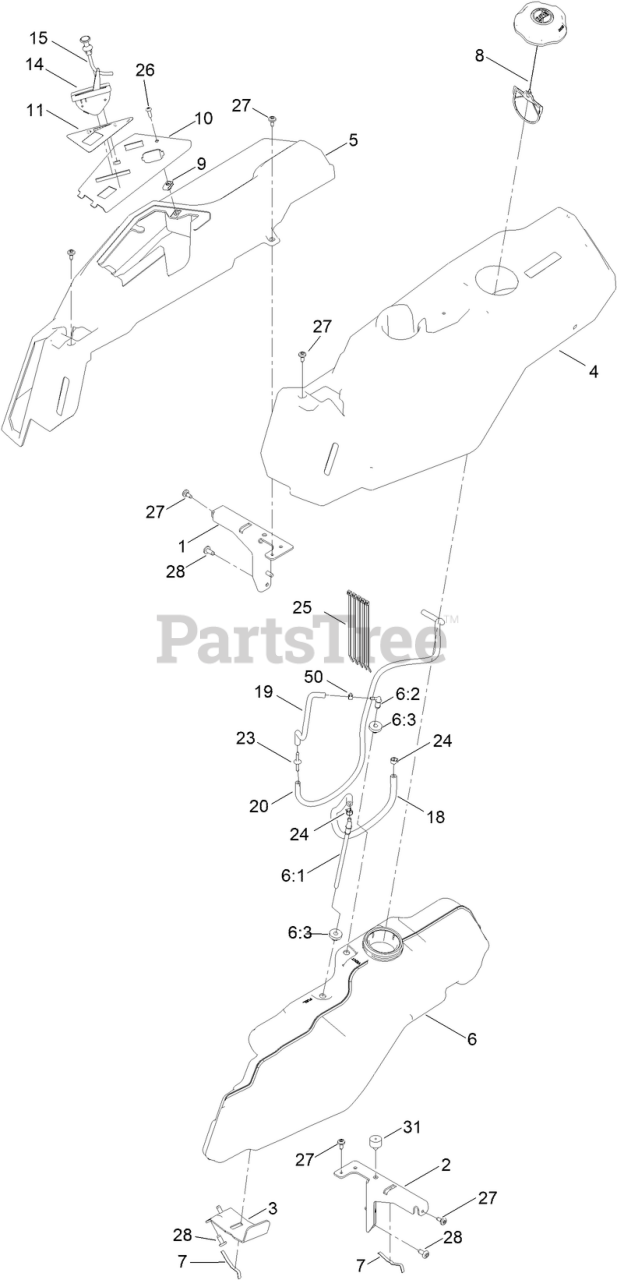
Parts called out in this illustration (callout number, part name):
1	SUPPORT-POD, RH
2	SUPPORT-POD, LH
3	SUPPORT-TANK, FUEL
4	POD-LH
5	POD-RH
6	TANK-FUEL ASM
6:1	CONNECTOR-ELBOW, 90 DEG
6:2	FITTING-ELBOW 90
6:3	BUSHING
7	SPRING
8	CAP-FUEL, RATCHETING
10	PANEL - CONTROL
11	DECAL-PANEL CONTROL
14	CABLE-THROTTLE
15	CABLE-CHOKE
18	HOSE-FUEL
19	HOSE-FUEL
23	ADAPTER ORIFICE
24	CLAMP-HOSE
25	TIE-CABLE
26	SCREW-PRH
27	SCREW-SHOULDER
31	BUMPER-GROMMET
50	CLAMP-HOSE
